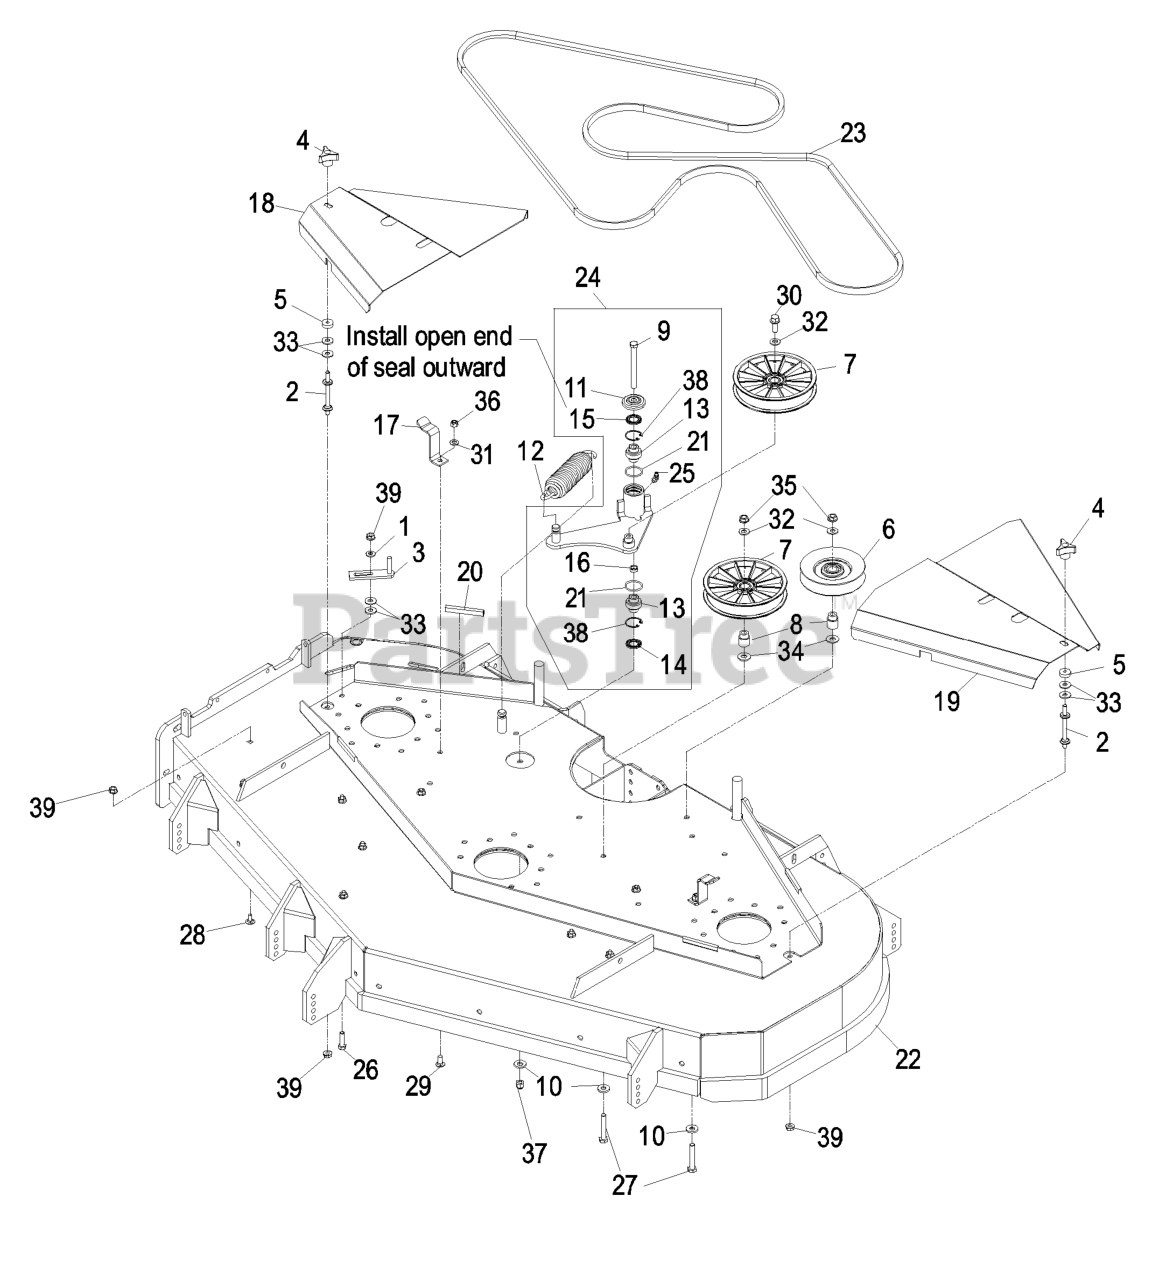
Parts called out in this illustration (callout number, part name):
1	WASHER-SPRING
2	STUD-SHIELD, BELT (SHORT)
3	GUIDE-BELT
4	KNOB-3 PRONG
6	PULLEY-IDLER
7	PULLEY,IDLER 6"
8	BUSHING-IDLER
9	SCREW-HH
10	WASHER-BELLEVILLE
11	GUARD-TOP
13	BEARING-SPHERICAL
14	SEAL-LIP, DOUBLE
15	SEAL-LIP, SINGLE
17	LATCH,BELT SHIELD
18	SHIELD, BELT RH 605 W/DEC
19	SHIELD, BELT LH 605 W/DEC
20	STRIP-SEAL
22	ASM, DECK 605 W/DECALS
23	BELT,BLADE DRIVE
24	KIT, IDLER ARM W/BEARINGS
25	FITTING-GREASE, 90 DEG
26	SCREW-HH
27	SCREW-HH
28	SCREW-CARR
29	SCREW-CARR
30	SCREW-HHF
31	WASHER-PLAIN
32	WASHER-FLAT
33	WASHER-FLAT
34	WASHER-FLAT
35	NUT-HHF, WHIZ
36	NUT-LOCK, NI
37	NUT-LOCK, NI
38	RING-SNAP
40	Asm, Deck Complete 60"
